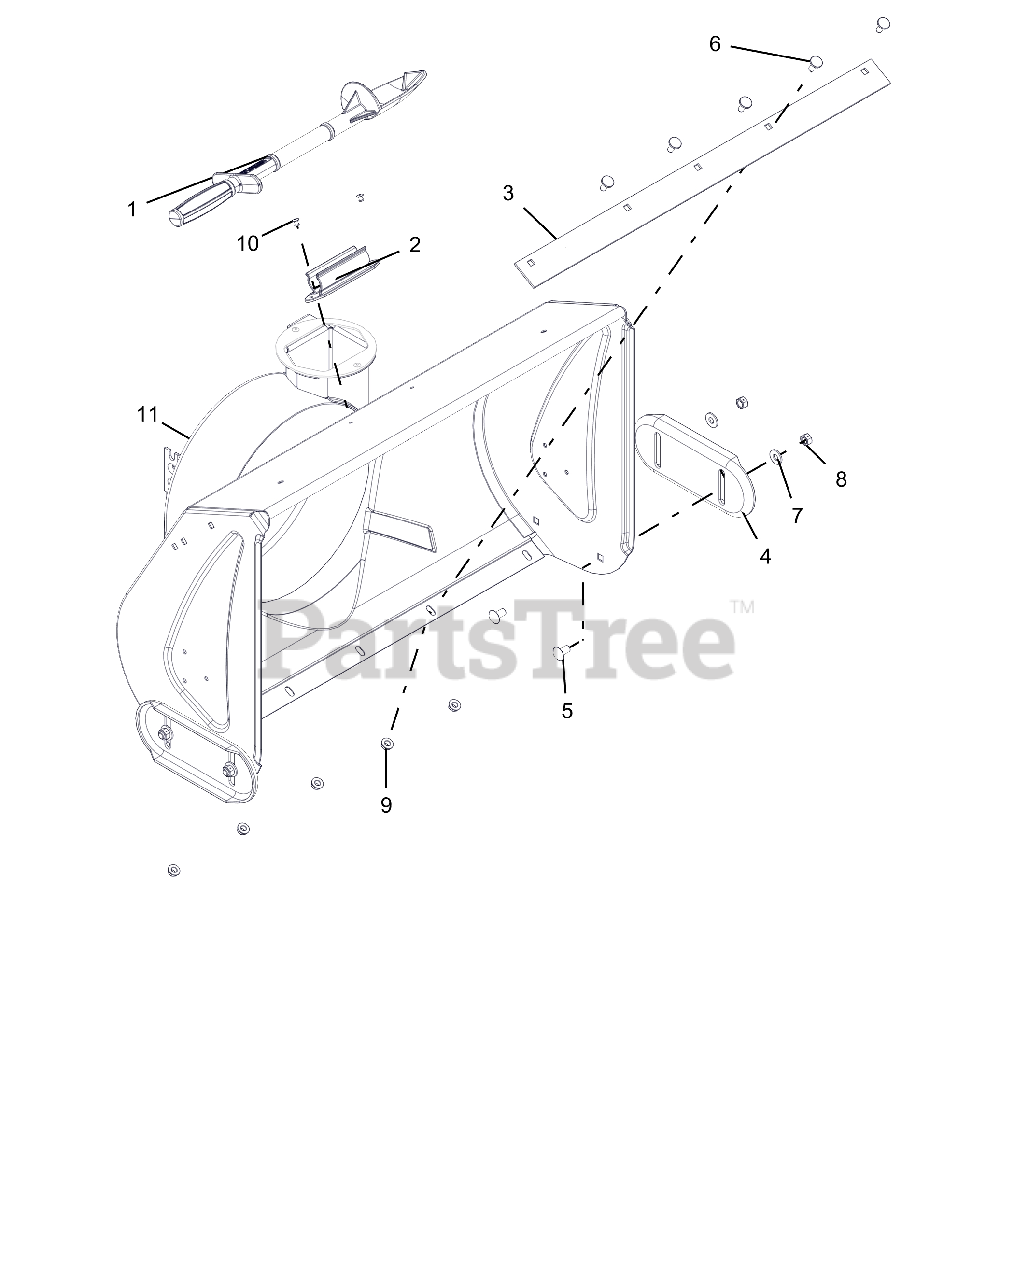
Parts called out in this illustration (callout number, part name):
1	DEVICE, SNOW CLEAN OUT
2	MOUNT, SNOW CLEAN OUT
3	SCRAPER BLADE, 28" COMPACT HI
4	SKID SHOE, REVERSIBLE
5	@BLT-RHDSSQNK .38-16X.75 G5YZ
6	BOLT, MODIFIED HEAD CARRIAGE
7	@WSHR-FL-STL.38X.875X.083 YWZC
8	@NUT-LK-CTR .38-16 YWZC
9	@NUT-LK-TOP-FLG .31-18 YWZC
10	RVT-POP .187 YZ
11	BLOWER HOUSING, 28"
